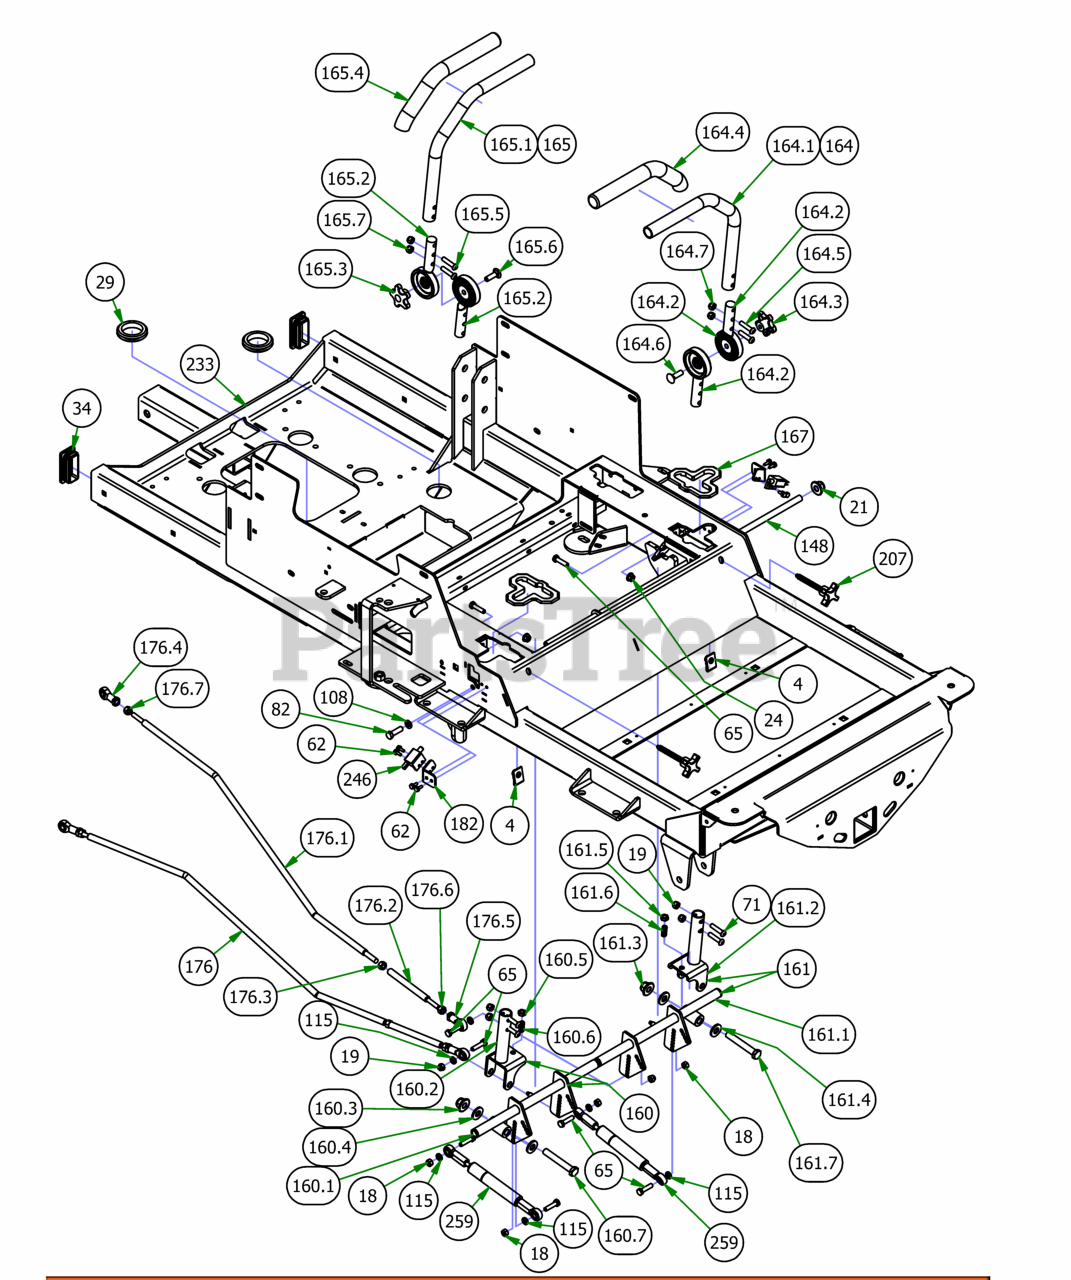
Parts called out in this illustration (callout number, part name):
4	Extruded Nut 3/8"-16 3/4" Hole Center With Patch
21	1/2-13 NYLON INSERT FLANGE LOCKNUT ZINC
24	5/16" Flange Nut
29	2019 2" x .25 Rubber Grommet
34	1 1/2 x 3 Frame Plug
62	12-24x 1/2 HWH Bolt
65	5/16 x 1 1/4 Hex Bolt
71	5/16-18 UNC X 1-3/8" BHCS, TORX DRIVE, GR 5
82	3/8" x 1 1/4" Hex Bolt
108	3/8" Lock Washer
115	5/16" Lock Washer
148	2019 Steering Actuator Rod
160	2019 R Series RH Arm Rod Assembly
160.1	2019 Drive Arm Actuator right
160.2	Drive Arm Pivot
160.3	1/2-13 NYLON INSERT FLANGE LOCKNUT ZINC
160.4	.505 Nylon Spacer
160.5	3/8-16 Half Jam Nut
160.6	3/8-16 x 1 Set Socket Set Screw Cup Point
160.7	1/2-13 x 3.25 GR 5 Hex Bolt Zinc
161	2019 R Series LH Arm Rod Assembly
161.1	2019 Drive Arm Actuator left
161.2	Drive Arm Pivot
161.3	1/2-13 NYLON INSERT FLANGE LOCKNUT ZINC
161.4	.505 Nylon Spacer
161.5	3/8-16 Half Jam Nut
161.6	3/8-16 x 1 Set Socket Set Screw Cup Point
161.7	1/2-13 x 3.25 GR 5 Hex Bolt Zinc
164	2019 Left Hand ADJ. Steering Arm Kit
164.1	2019 Steering Arm Grip
164.2	2019 Steering Arm Adjuster Casting
164.3	Black Knob for Adjustable Steering Arm
164.4	Black Steering Arm Grip
164.5	5/16-18 UNC X 1-3/8" BHCS, TORX DRIVE, GR 5
164.6	3/8" x 1 1/4" Carriage Bolt
164.7	5/16-18 Nylock Insert Locknut
165	2019 Right Hand ADJ. Steering Arm Kit
165.1	2019 Steering Arm Grip
165.2	2019 Steering Arm Adjuster Casting
165.3	Black Knob for Adjustable Steering Arm
165.4	Black Steering Arm Grip
165.5	5/16-18 UNC X 1-3/8" BHCS, TORX DRIVE, GR 5
165.6	3/8" x 1 1/4" Carriage Bolt
165.7	5/16-18 Nylock Insert Locknut
167	Snap-In Bushing-2019
176	2019 Renegade Push Rod Assembly
176.1	2019 Renegade Push Rod
176.2	2019 Renegade Push Rod Adjuster
176.3	3/8" Fine Threaded Jam Nut
176.4	Spherical Rod End - Outlaw
176.5	Spherical Rod End - Outlaw
176.6	5/16" LH Fine Threaded Jam Nut
176.7	5/16" RH Fine Threaded Jam Nut
182	2019 Arm Switch Bracket
207	Speed Limiting Knob 3/8-16X 3"
233	2019 Renegade Diesel Frame - Powdercoated
246	Safety Switch
259	2019 SROID Damper With Spherical Rod Ends
